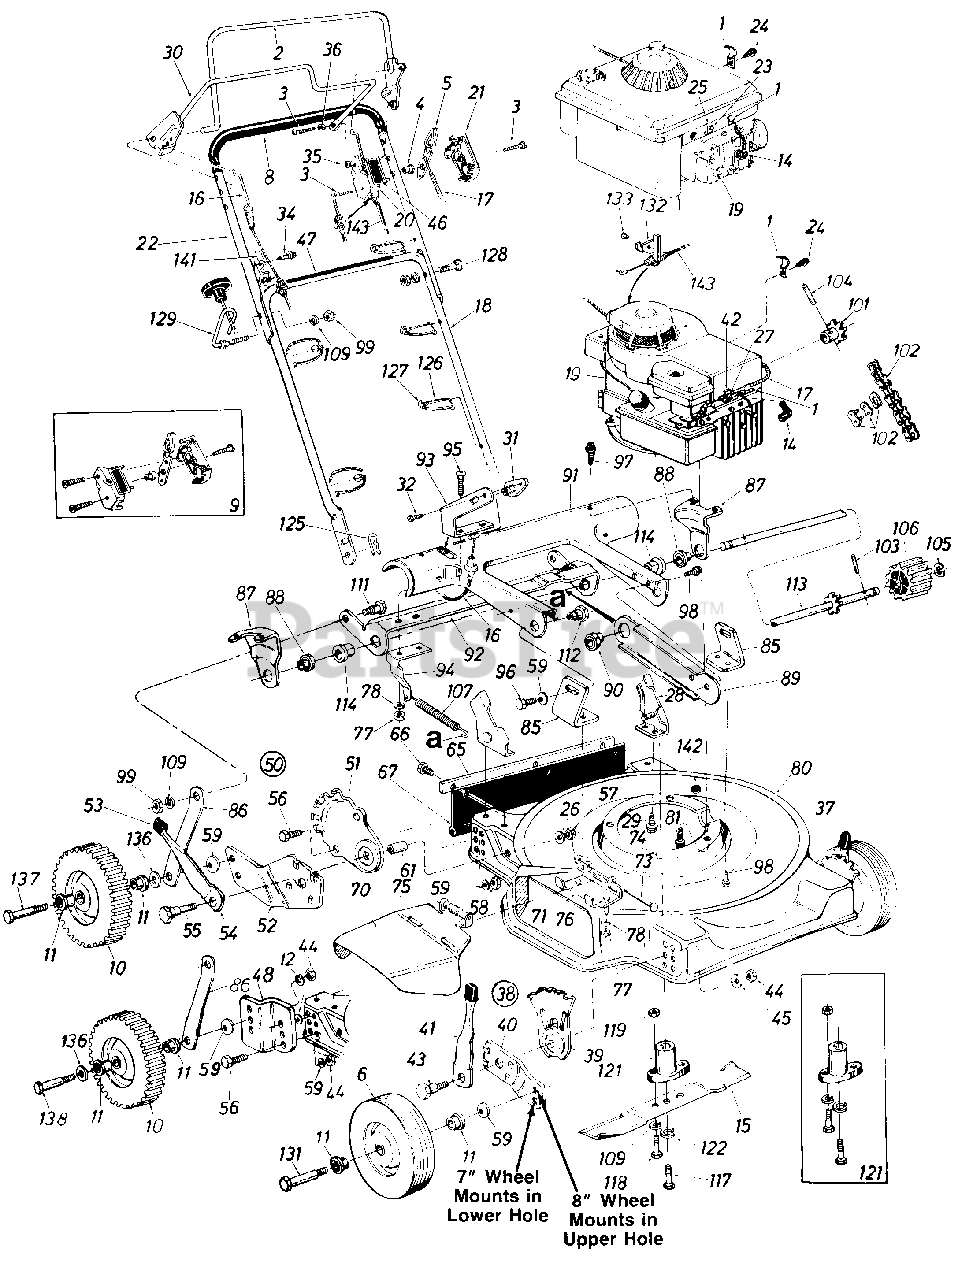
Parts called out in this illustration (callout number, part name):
1	Casing Clamp
2	Control Handle Ass'y.-L.H.
3	Truss Mach. Hi-B Tap Scr. #12 x 1.5"
4	Control Disc Pin
5	Throttle Control Lever
6	Front Wheel Ass'y. Comp.
8	Grip
9	Control Housing Comp.
10	Rear Wheel Ass'y. Comp.
11	Fl. Ball Brg. 1/2" I.D.
12	L-Wash 3/8" 1 D
14	Spark Plug Insulator
15	22" Blade
16	Clutch Cable w/Spring-32"
17	Throttle Wire-53"
18	Lower Handle (Chrome)
19	Engine
20	Clutch Panel Half
21	Control Panel Half
22	Upper Handle (Chrome)
23	Hex AB-Tap Scr. #8 x .50"
24	Hex B-Tap Scr. #10 x .38"
25	Casing Clamp
26	Bell-Wash. 5/16" I.D.
27	Hex "B"-Tap Scr. #10 x .38"
28	Handle Brkt. Ass'y-L.H.
29	Hex B-Tap Scr. 5/16-18 x .5"
30	S.P. Bail Ass'y.
31	Barrel Cable Hold-Down R.H.
32	B-Tap Scr. #10 x .38 Lg.
34	Hex Wash. AB-Tap Scr. 5/16 x .75"
35	Spr-Wash. .206 I.D. x .448
36	Spacer .23 I.D. x .30 O.D.
37	Front Height Adj. Ass'y.-L.H.
38	Front Height Adj. Ass'y.-R.H.
39	Height Adj. Plate
40	Pivot Bar
41	Spring Lever Ass'y. w/Knob
42	Casing Clamp
43	Shld. Bolt .50 Dia. x .430
44	Hex Nut 3/8-16 Thd.
45	Bell-Wash. .39 I.D. x 1.38 O.D.
46	Control Label
47	Instruction Label
48	Wheel Brkt.
50	Rear Height Adj. Ass'y.-R.H.
51	Index Plate
52	Pivot Bar-R.H.
53	Spring Lever Knob
54	Spring Lever
55	Shld. Bolt .50 Dia. x .433
56	Hex Bolt 3/8-16 x .75
57	Hex Cent. L-Nut 5/16-18 Thd.
58	Hex Nut 3/8-16 Thd.
59	Bell-Wash. .40 I.D. x .88 O.D.
61	Spacer .383 I.D. x .503 O.D.
65	Retaining Strip
66	Hex AB-Tap Scr. 1/4 x .62
67	Rear Flap Ass'y.
70	Chute Deflector Ass'y.
71	Adapter Plate
73	Pivot Pin
74	Push Nut 1/4"
75	Torsion Spring
76	Hex Bolt 1/4-20 x .50 Lg.
77	Hex Nut 1/4-20 Thd.
78	L-Wash. 1/4 I.D.
80	22" Deck Ass'y.
81	Hex TT-Tap Scr. 3/8-16 x 1.0
85	Pivot Brkt.
86	Link 4.58
87	Axle Brkt.
88	Fl. Ball Brg. 1/2" I.D.
89	Brg. Support
90	Fl. Ball Brg. 1/2" I.D.
91	Pinion-Pivot Cover
92	Drive Engagement Cam
93	Engagement Arm-L.H.
94	Spring Bracket
95	Carriage Bolt 1/4-20 x .62
96	Hex Bolt 3/8-16 x .50 Lg.
97	Hex AB-Tap Scr. 1/4 x .62
98	Hex AB-Tap 1/4 x .62"
99	Hex Nut 5/16-18 Thd.*
101	1OT Sprocket Ass'y.
102	#48 Chain 1/2" Pitch 50 Links
103	Spring Pin Spir. 3/16 Dia. x 1 .25
104	Spring Pin Spir. 3/16 Dia. x 1.0
105	E-Ring For .500 Dia. Shaft
106	Drive Pinion
107	Extension Spring 4.25 Lg.
109	L-Wash. 5/16 I.D.
111	Shld. Bolt .437 Dia. x .162
112	Shld. Nut .625 Dia. x .165
113	Pinion Shaft w/7T Sprocket
114	Fl. Ball Brg. .501 I.D.
117	Hex Bolt 3/8-24 x 2.25
118	Hex Bolt 5/16-24 x 1.0-Spec.
119	Hex Nut 5/16-24 Thd.
121	Blade Adapter Kit
122	L-Wash. 3/8 I.D.-H.D.
125	Intern. Cot. Pin 5/16 Dia.
126	Cable Tie
127	Cable Anchor
128	Curved Carriage Bolt 5/16-18 x 1.38" Lg.
129	Rope Guide Bolt
131	Front Axle Bolt
132	Cable Bracket
133	Pop Rivet .156" Dia. x .379
136	Fl-Wash. .531 I.D. x .93 O.D.
137	Rear Axle Bolt
138	Rear Axle Bolt
141	Cabe Brkt.
142	Plastic Plug
143	Control Cable-39" (Green)
